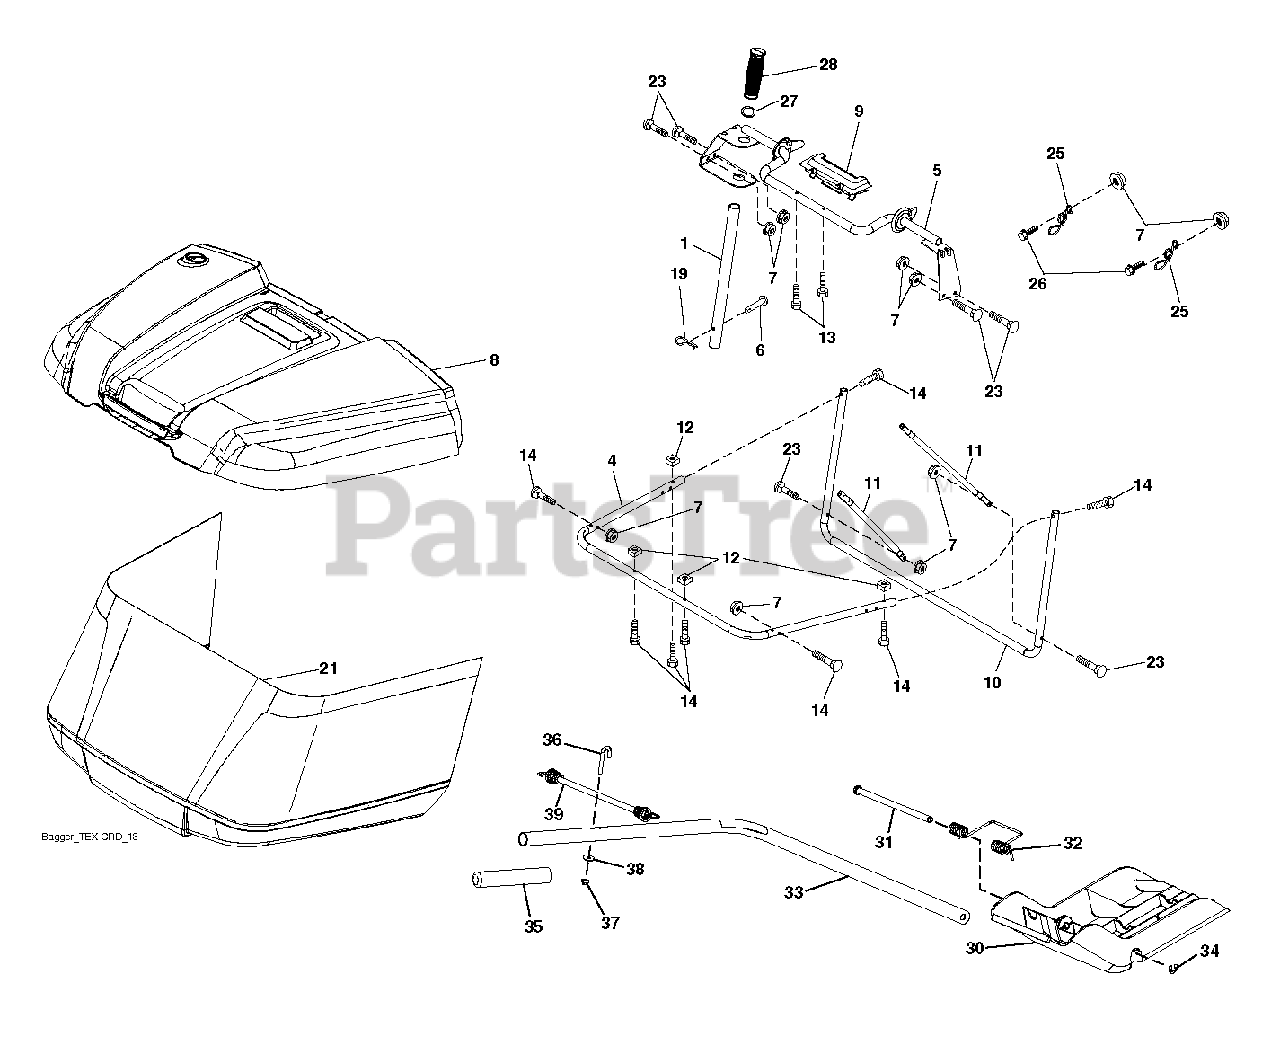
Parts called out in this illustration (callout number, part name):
1	TUBE.PNT.HDL.BAGGER.
6	RIVET,DRILLED
7	NUT T
19	PIN.COTTER.5/16.BOW TI
26	SCREW HEX CRT
28	GRIP.HANDLE.BLACK
34	E-RING.5/16"
38	WASHER
